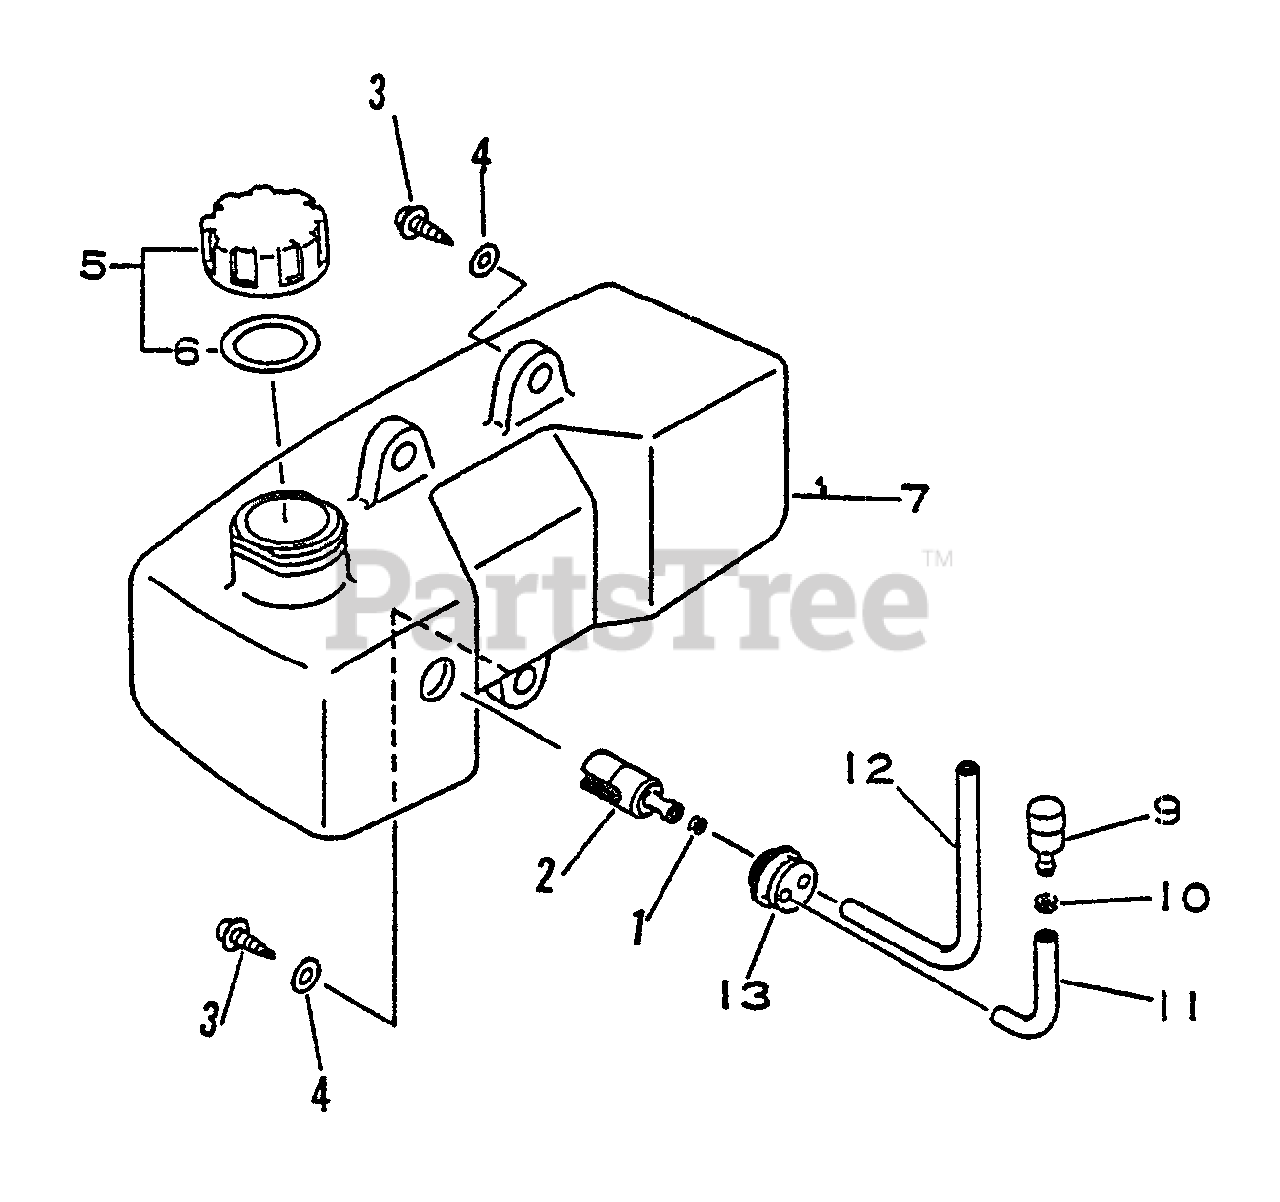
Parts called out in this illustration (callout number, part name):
1	CLIP 6 MM
2	FILTER, FUEL
3	SCREW 5×14
4	WASHER 5.5×12×0.8
5	CAP ASSY
6	GASKET, FUEL CAP
7	TANK, FUEL
9	VENT ASSY
10	RETAINER, PIPE
11	PIPE, FUEL 3x-5x-70 BLACK
12	PIPE, FUEL 3×5×210 BLACK
13	GROMMET, FUEL
